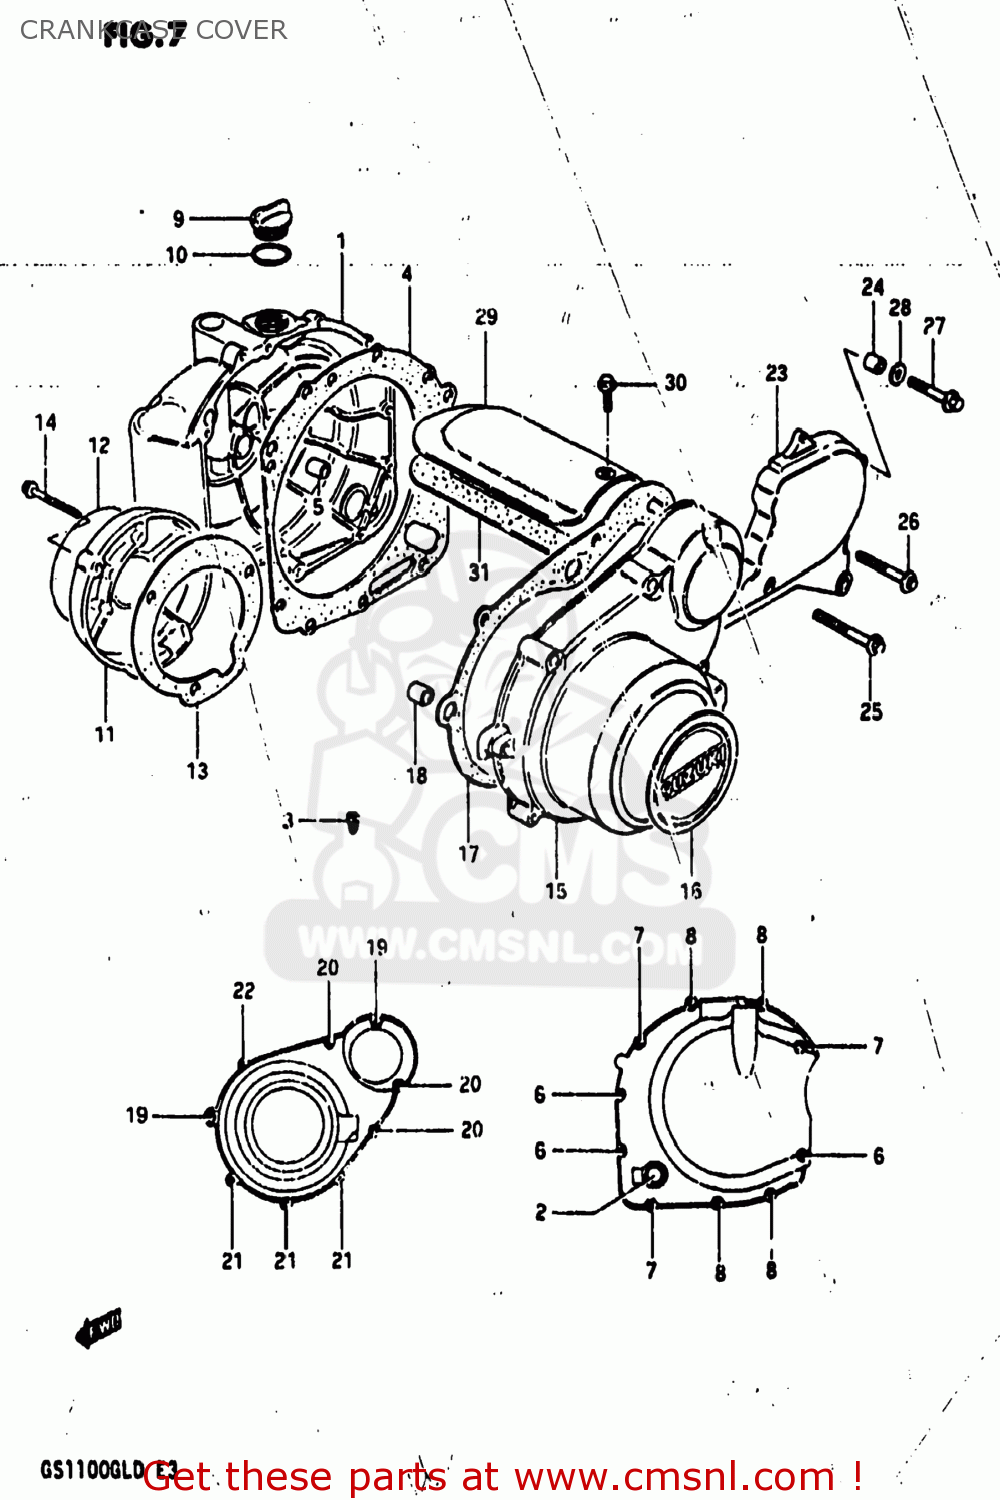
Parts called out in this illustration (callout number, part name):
1	COVER,CLUTCH
2	LENS,OIL LEVEL CHECK
3	JET
4	GASKET,MAGNETO COVER (N (MCA)
5	PIN
6	BOLT (6X35)
7	BOLT (6X30)
8	BOLT
9	CAP
10	O RING(D:2.2,ID:32)
11	COVER,CONTACT BREAKER
12	EMBLEM,CONTACT BREAKER COVER
13	GASKET,CONTACT BREAKER COVER (NAS)
14	BOLT (5X30)
15	COVER,MAGNETO
16	EMBLEM,MAGNETO COVER
17	GASKET,MAGNETO COVER (MCA)
18	PIN
19	BOLT
20	BOLT (6X40)
21	BOLT (6X35)
22	BOLT (6X30)
23	COVER,SECONDARY DRIVE
24	PIN
25	BOLT (6X30)
26	BOLT
27	BOLT (6X20)
28	WASHER
29	COVER,STARTER MOTOR
30	BOLT
31	GASKET,STARTER MOTOR COVER (MCA)
